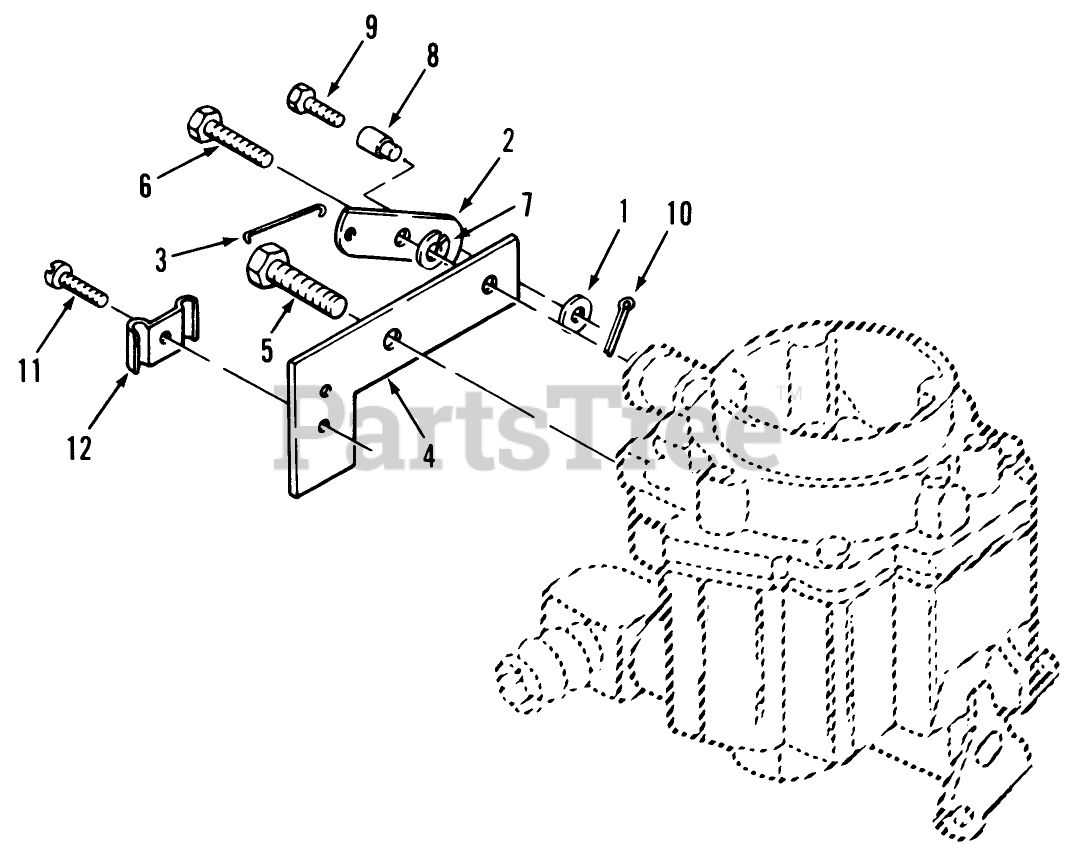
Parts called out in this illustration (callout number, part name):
1	Washer
2	SWIVEL-CHOKE
3	LINK-CHOKE
4	BRACKET
5	SCREW-HWH
6	BOLT-SHOULDER
7	WASHER-LOCK
8	SWIVEL
9	SCREW
10	PIN-COTTER
11	SCREW-TAPPING
